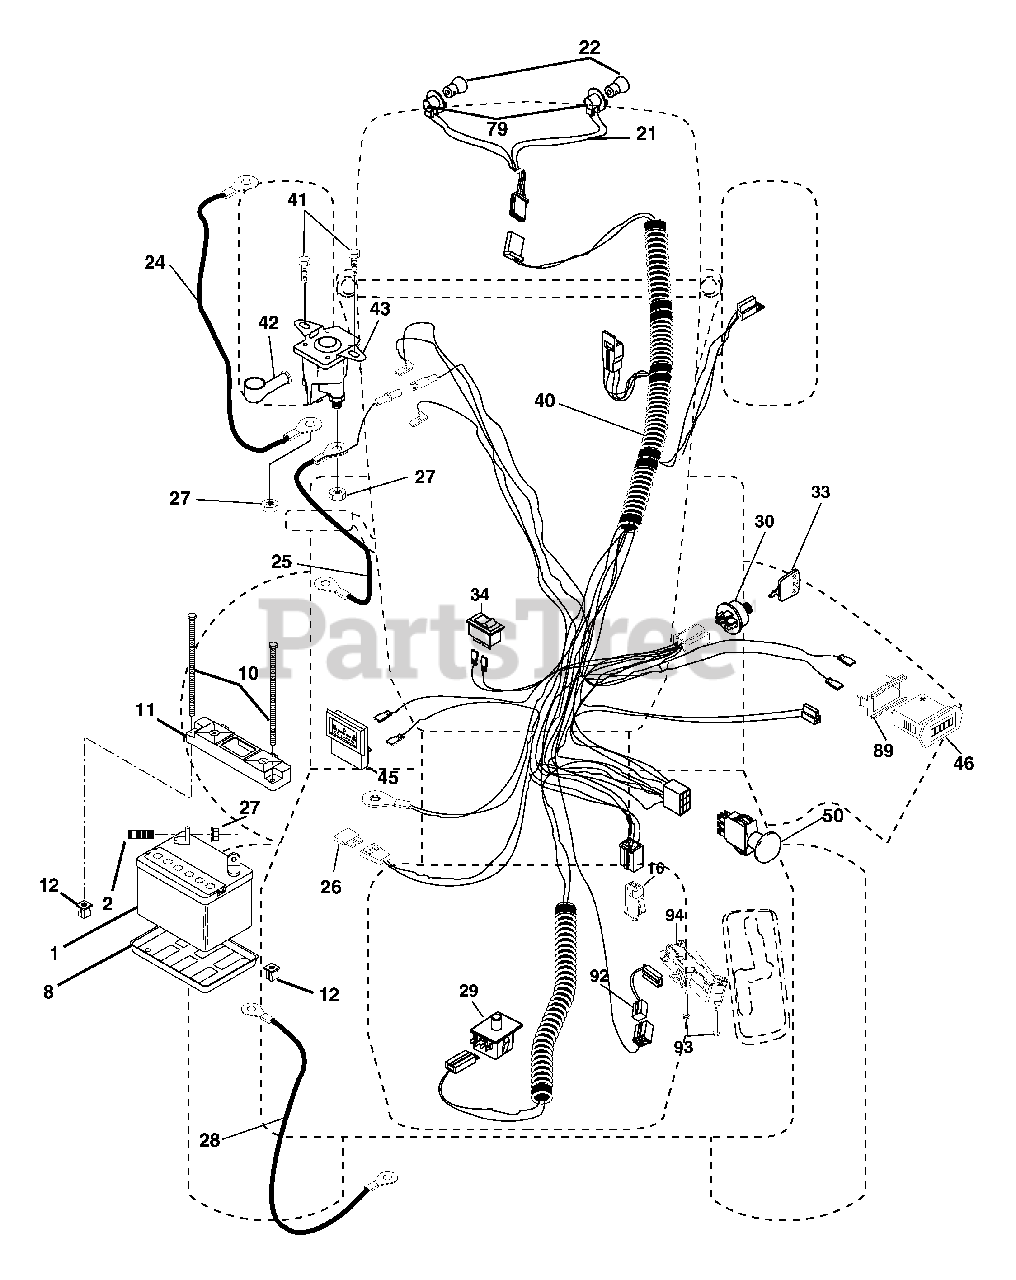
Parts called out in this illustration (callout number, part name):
1	Battery
2	Bolt Hex Head 1/4-20 x 3/4
8	Tray, Battery
10	Bolt Btr Frt 1/4-20 x 7.5 zinc
11	Holdown Battery Front Mount
12	Nut Push Nylon 1/4"
16	Switch Interlock Push-In
21	Harness Headlight w/Bulbs
22	Bulb Light
24	Cable 6 Ga. Red 12.5" w.16 Wire
25	Cable, Battery
26	Fuse
27	Nut Keps Hex 1/4-20 unc
28	Cable, Ground
29	Switch, Seat
30	Switch, Ign
33	Key
34	Switch Light/Reset
40	Harness, Ignition
41	Screw Thd Cut 1/4-20 x 1/2
42	Cover, Terminal
43	Solenoid
45	Ammeter
46	Hourmeter Snap-In
50	Switch, PTO
79	Socket, Light Bulb
89	Bracket Snap-In
92	Harness Pigtail Reverse Switch
93	Screw Plastite 10-14 x 2.0
94	Module Reverse ROS
